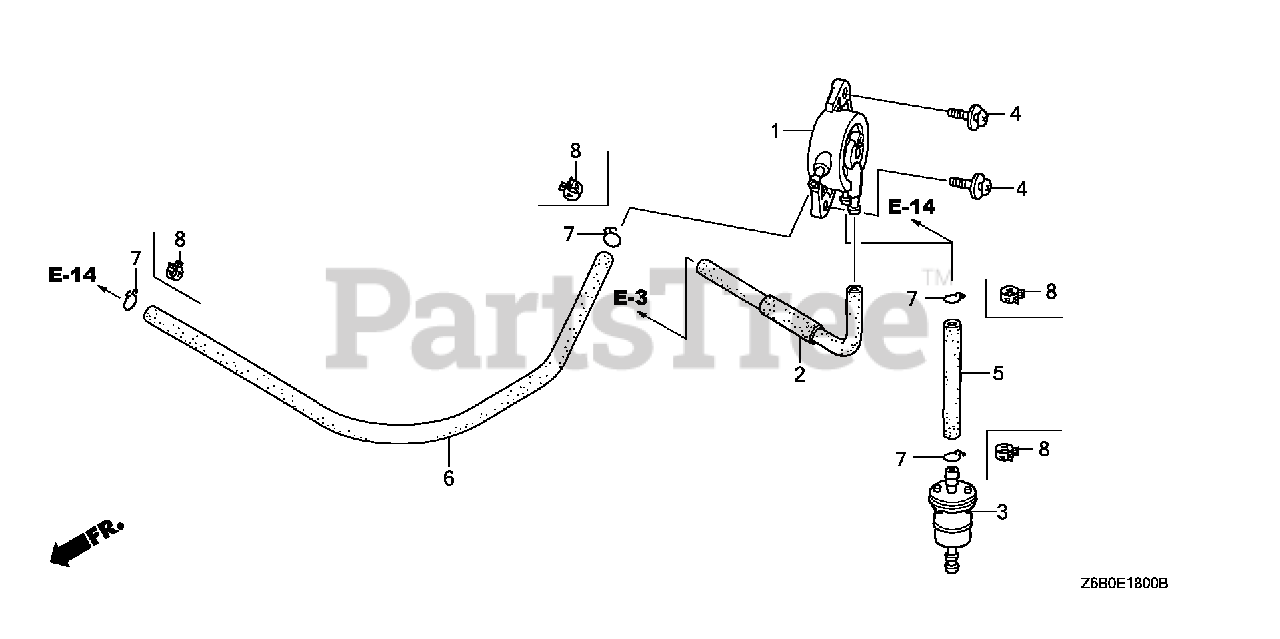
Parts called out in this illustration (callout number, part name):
1	PUMP ASSY., FUEL
1	PUMP ASSY., FUEL (MSDS)
2	TUBE, DIAPHRAGM
3	FILTER, FUEL
3	STRAINER, FUEL
4	SCREW-WASHER (5X16)
5	TUBE, FUEL (5.3X100) (FKM)
5	BULK HOSE, FUEL (5.5X3000) (5.3X100)
6	TUBE, FUEL (5.3X350) (FKM)
6	BULK HOSE, FUEL (5.5X3000) (5.3X350)
7	CLIP, TUBE (B10)
8	CLAMP, TUBE (D10)
